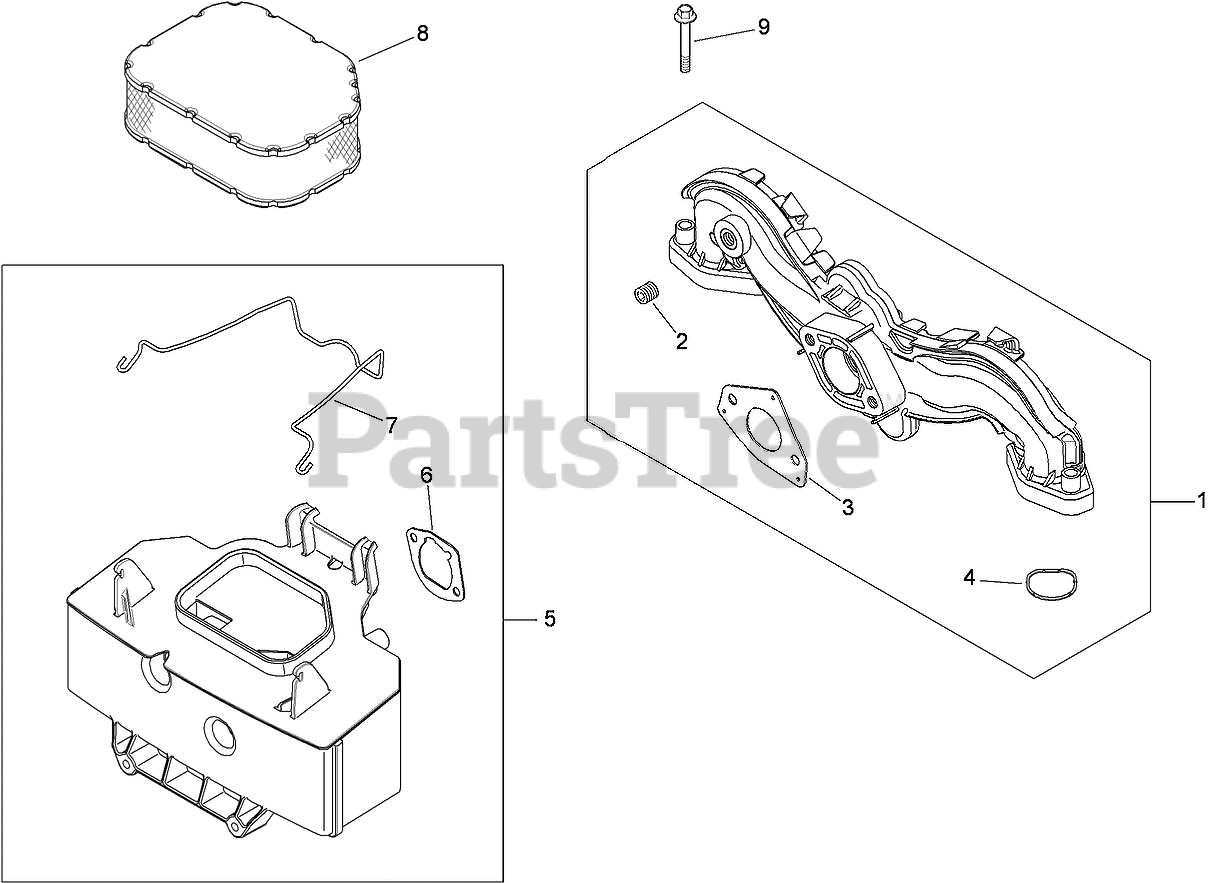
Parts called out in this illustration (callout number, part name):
1	INTAKE MANIFOLD ASM (INCLUDES 2-4)
2	GASKET-CARBURETOR
3	O-RING (INTAKE PORT)
4	PLUG-PIPE, COUNTERSUNK (1/8)
5	AIR CLEANER BASE KIT (INCLUDES 6, 7)
6	GASKET-BASE, AIR CLEANER
7	LATCH-ELEMENT, AIR CLEANER
8	ELEMENT-FILTER, AIR
9	SCREW-FLANGE (M6X1.0X40)
